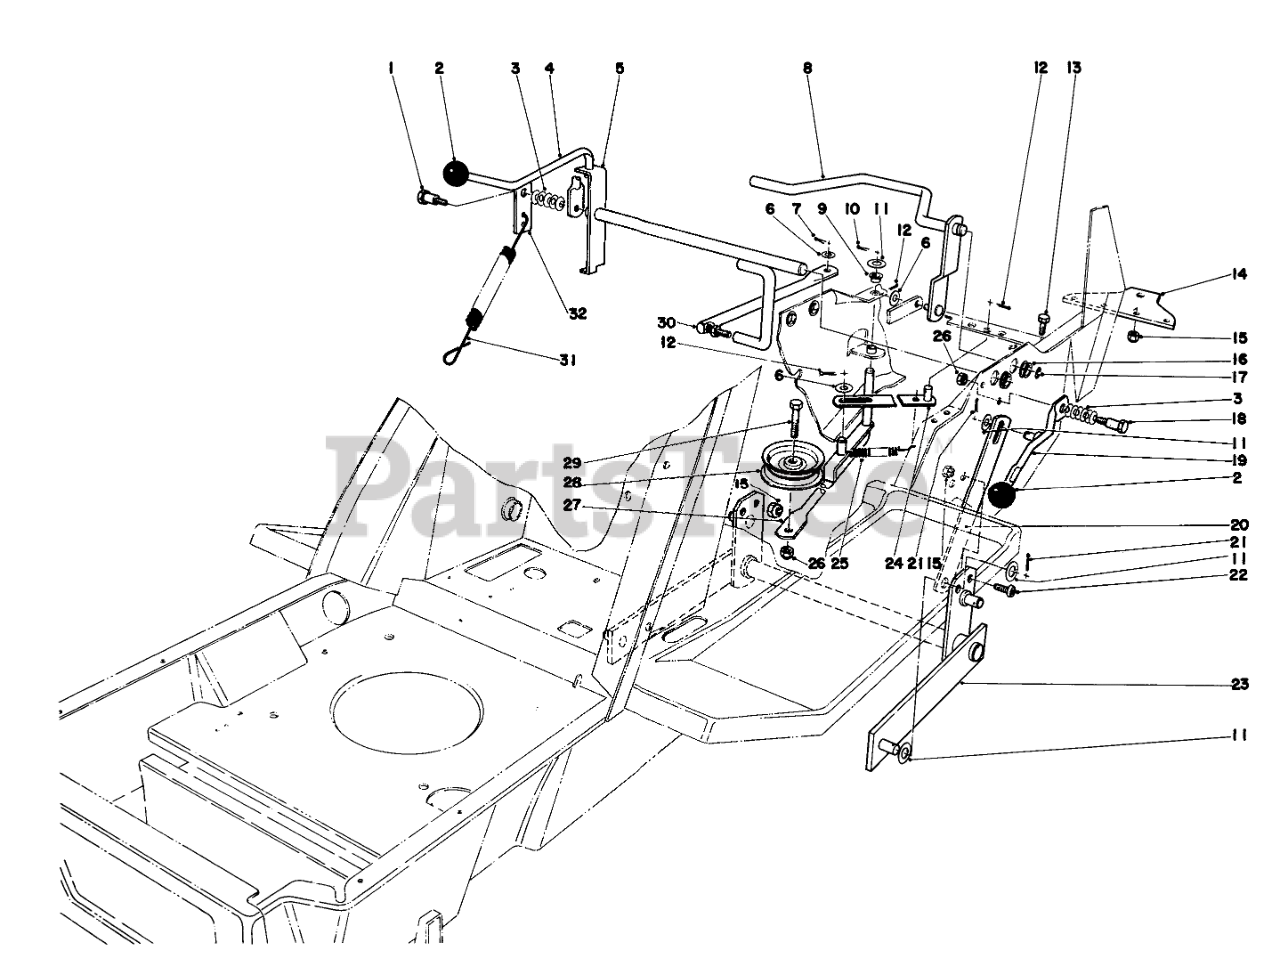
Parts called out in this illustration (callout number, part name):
1	BOLT-SHOULDER
2	Knob
3	Belleville Washer
4	SHIFT LEVER BO
5	Shim Lever
6	WASHER-PLAIN
7	PIN-COTTER
8	CLUTCH ACTUATOR WA B
9	BUSHING-NYLINER
10	PIN-COTTER
11	WASHER-FLAT
12	PIN-COTTER
13	SCREW-HHF
14	HITCH PLATE R
15	NUT-LOCK, NI
16	Nyliner
17	E-RING
18	Shoulder Bolt
19	Handle-Height of Cut
20	HOC LINK B
21	PIN-COTTER
22	SCREW-HSBH
23	Pivot Bar
24	SPRING RET WA B
25	DECK TENSION SPRNG O
26	NUT-LOCK, CONE
27	IDLER ARM WA BO
28	IDLER PULLEY
29	SCREW-HH
30	SHIFT ARM BO
31	Spring Extension
32	Bracket Counterbalance Spring
